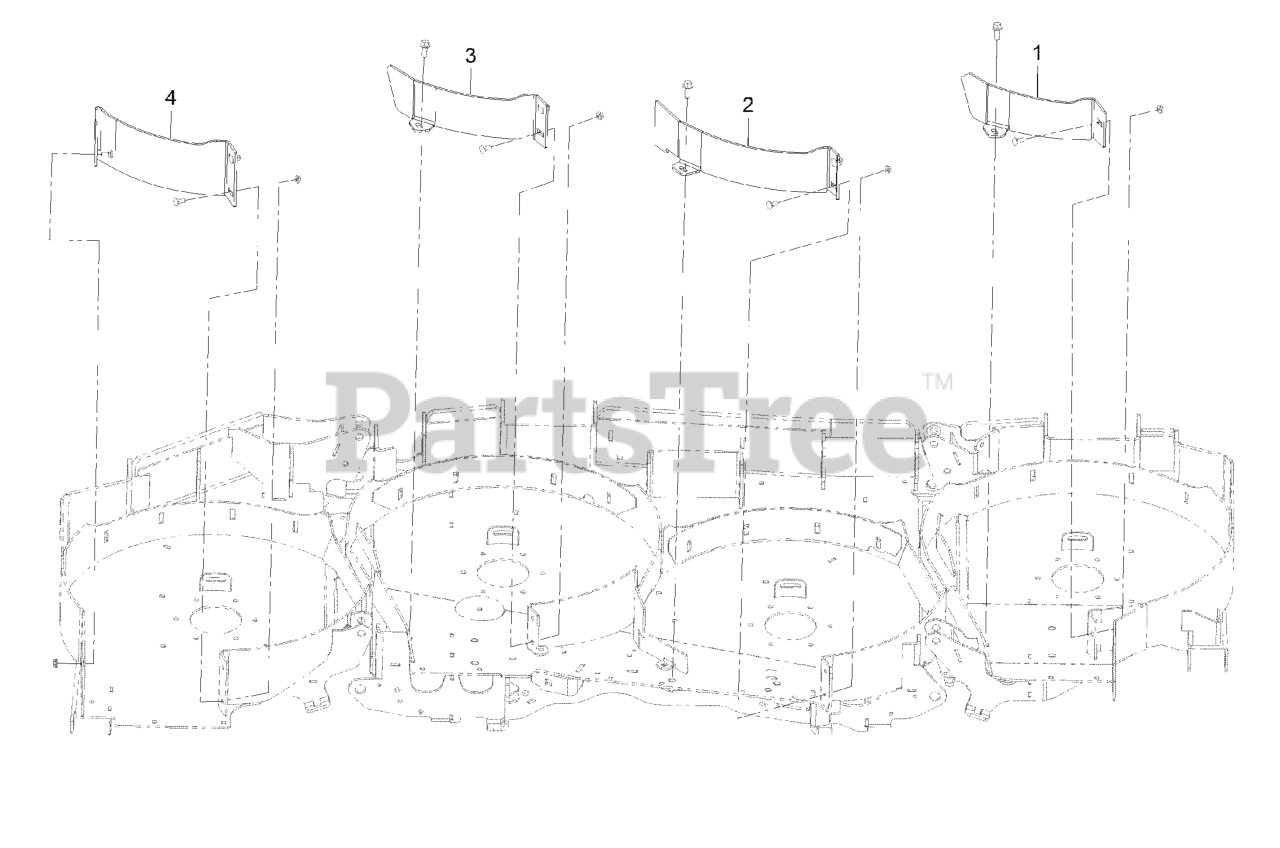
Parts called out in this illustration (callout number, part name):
1	BAFFLE-BLOCK, LH WING
2	BAFFLE-BLOCK, LH CTR
3	BAFFLE-BLOCK, RH CTR
4	BAFFLE-BLOCK, RH WING
